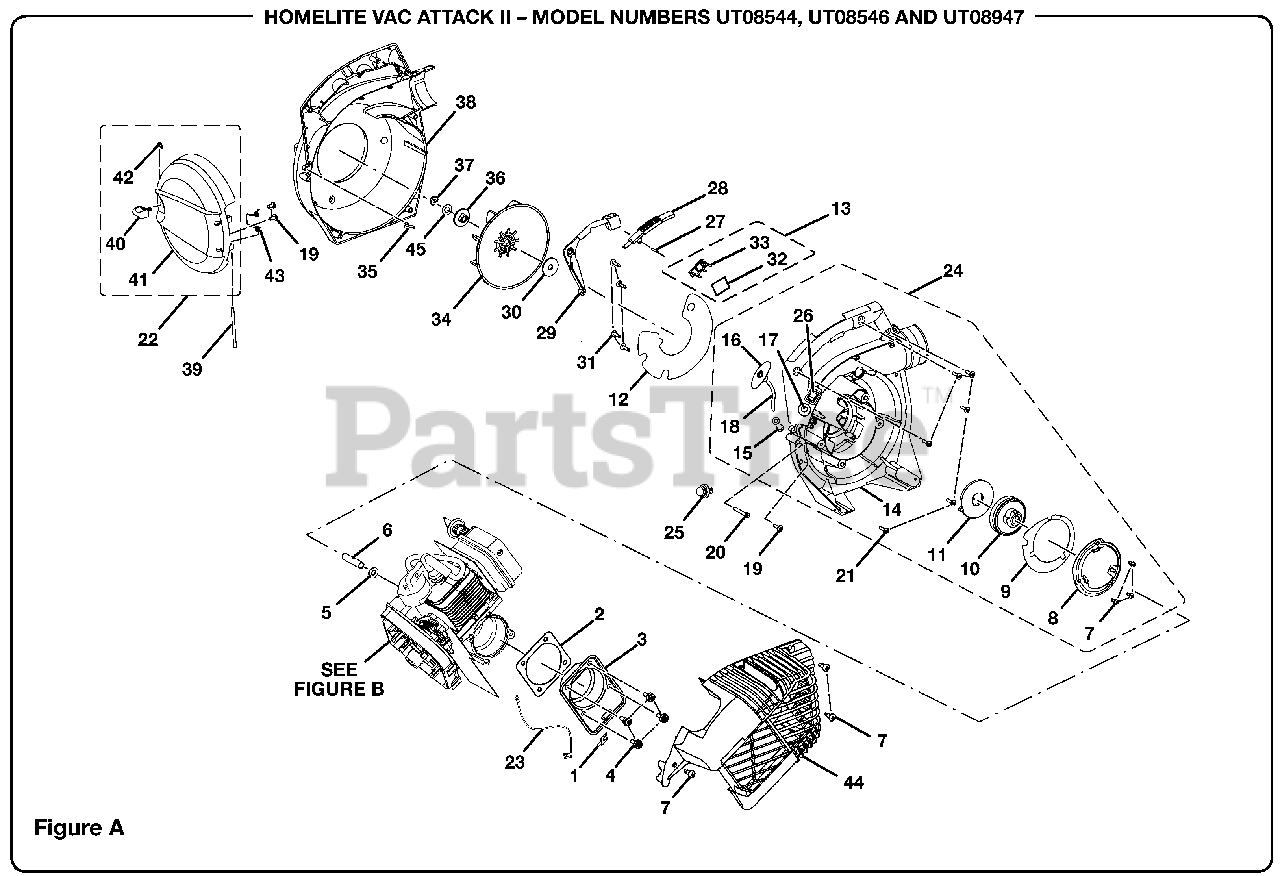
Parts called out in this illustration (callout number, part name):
2	Crankcase Gasket
3	Crankcase Cover
4	Screw (10-24 X 9/16 in. Pan Hd.)
5	Flat Washer
6	Fan Spacer
7	Screw (#8 X 1/2 in. Pan Hd.)
8	Baffle
9	Baffle Gasket
10	Pully
11	Spring & Container
12	Inner Volute Seal
13	Screen Cover & Netting Assembly
14	Inner Volute Housing
15	Bushing - Starter Rope
16	Starter Grip
17	Bushing
18	Starter Rope
19	Screw (10-14 x 1/2 in.)
20	Screw (10 X 1-5/8 in. Hex Hd.)
21	Screw (10-14 X 3/4 in. Torx Truss Hd.)
22	Door & Knob & E-ring Assembly
23	Lead W/terminals
24	Inner Housing & Starter Assembly
25	Primer Bulb
26	Switch
27	Slide Pin
30	Flat Washer
31	Screw (10-24 X 3/4 in. Truss Hd.)
32	Mesh Netting
33	Screen Cover
34	Fan
35	Wire Loop
36	Fan Adaptor
37	Lock Nut (3/8-24)
38	Outer Volute
39	Door Hinge Shaft
41	Blower Knob
43	Door Hinge Spring
44	Blower Shroud
